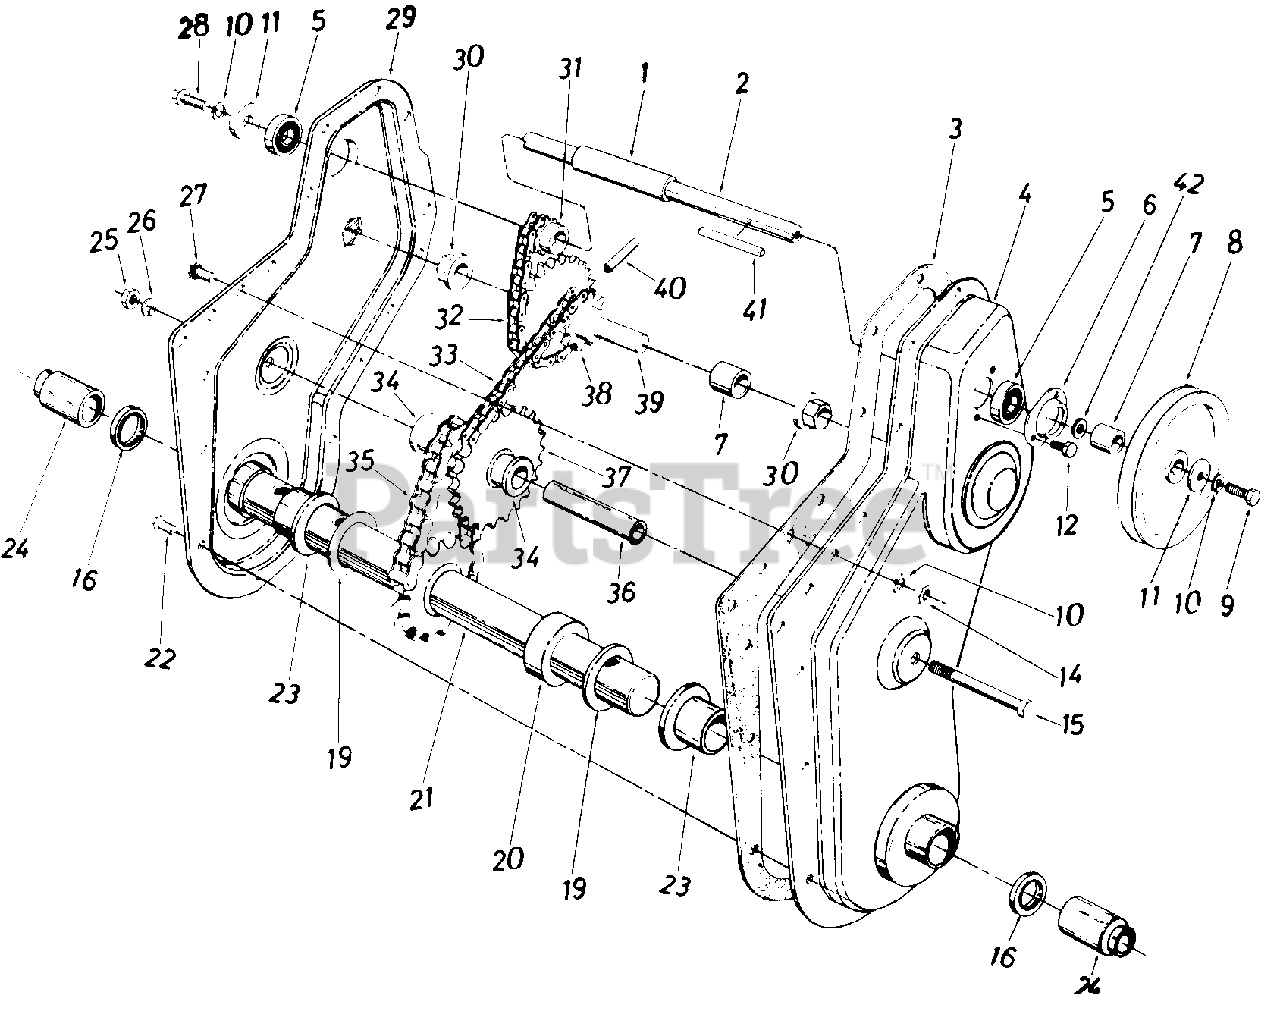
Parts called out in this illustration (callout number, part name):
1	Spacer .657 I.D. x .78 O.D. x 2.19
2	Jack Shaft
3	Gasket for Housing
4	Housing Half-L.H.
5	Ball Bearing .625 I.D. x 1.375 O.D.
6	Bearing Housing
7	Spacer .625 I.D. x .88 O.D. x 1.035
8	Chain Case Pulley 4.5" Dia.
9	Hex Scr. 5/16-18 x .88" Lg. Special
10	L-Wash. 5116" I.D.
11	Fl-Wash. 5/16 I.D. x 1.125 O.D. x .125
12	Hex Wash. Hd. Self-Tap Scr. 1/4-20 x .50" Lg.
14	Hex Nut 5/16-18 Thd.
15	Hex Scr. 3/8-16 x 3.25" Lg.
16	Oil Seal 1" I.D. x 1.357 O.D.
19	Fl-Wash. l.0" I.D. x 1.62 O.D. x .090
20	Spacer 1.0" I.D. x 2.0" O.D. x .68
21	Tine Shaft Ass'y.
22	Hex Bolt 1/4-28 x .62" Lg.
23	Flange Bearing (Plastic)
24	Dust Cap
25	Hex Nut 3/8-16 Thd.
26	L-Wash. 3/8" I.D.
27	Hex Sems Scr. 5/16-18 x 1.00" Lg.
28	Hex Scr. 5/16-18 x .62" Lg. Special
29	Housing Half-R.H.
30	Hex Flanged Bearing .630 I.D.
31	Sprocket 10 Teeth x .500 Pitch
32	#41 Chain 1/2" Pitch x 34 Links-Endless
33	#420 Chain 1/2" Pitch x 48 Links-Endless
34	Flange Bearing .628 I.D.
35	#50 Chain 5/8" Pitch x 28 Links-Endless
36	Sprocket Shaft
37	Sprocket Bearing Sleeve Ass'y.
38	Sprocket Sleeve Ass'y.
39	Sprocket Shaft
40	Spring Pin Spiral 1/4" Dia. x 1.5" Lg.
41	Sq. Key 3/16 x 1.50" Lg.
42	Fl-Wash.
